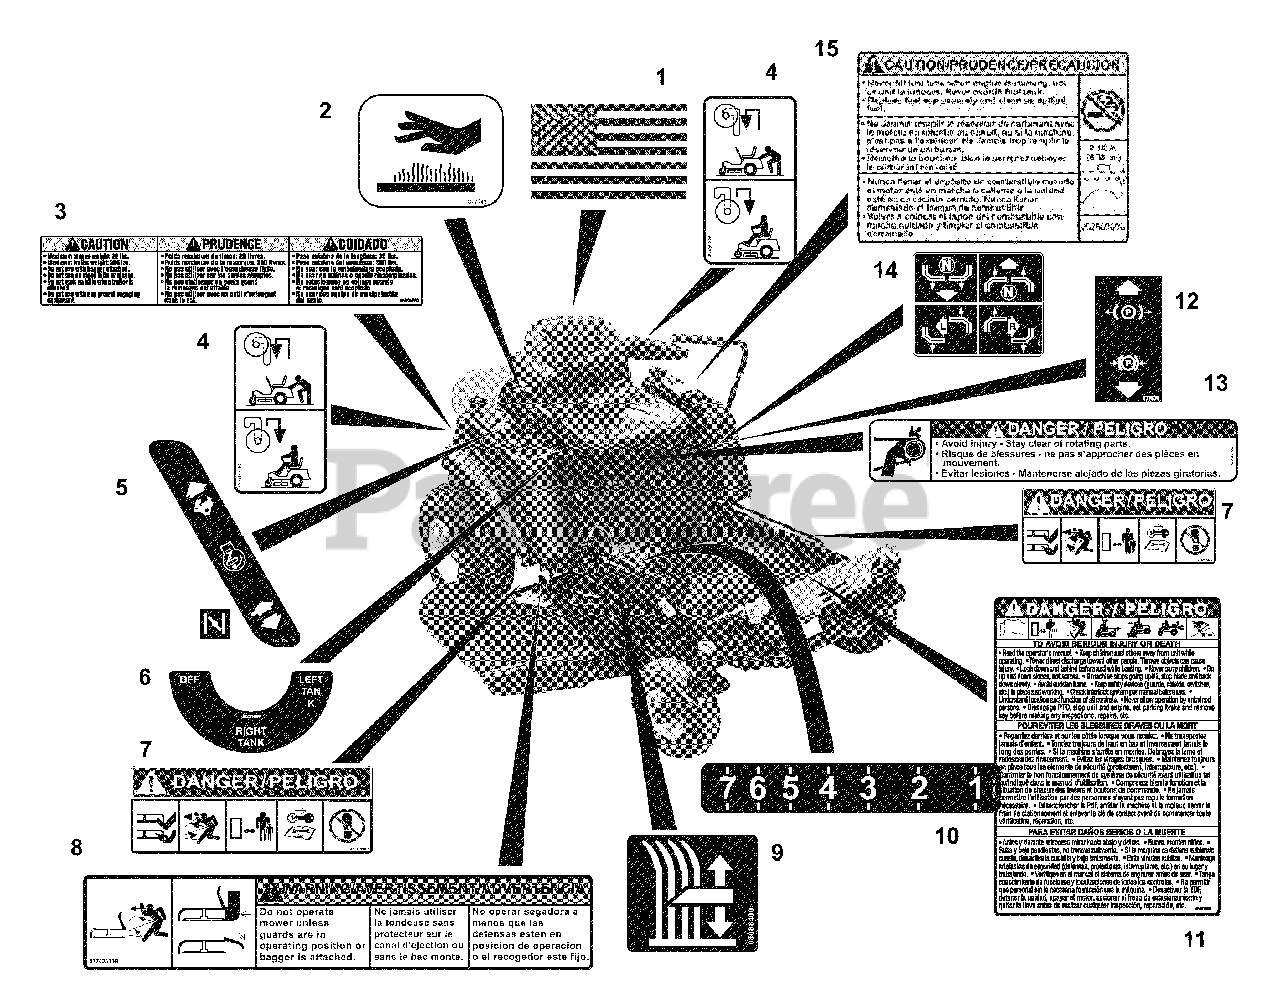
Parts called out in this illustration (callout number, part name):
1	DECAL, AMERICAN FLAG
2	DECAL, HOT SURFACE
3	DECAL, TRAILER HITCH
4	DECAL, TRANSMISSION DISCONNECT
5	DECAL, SPEED CONTROL
6	DECAL, FUEL VALVE
7	DECAL, MOWER PAN DANGER
8	DECAL, WARNING
9	DECAL-CUT HEIGHT
10	DECAL CUT HEIGHT
11	DECAL, DANGER BILINGUAL
12	DECAL, PARKING BRAKE LEVER
13	DECAL- DANGER
14	DECAL, INSTRUCTIONAL-STEERING
15	DECAL,FUEL WARNING
